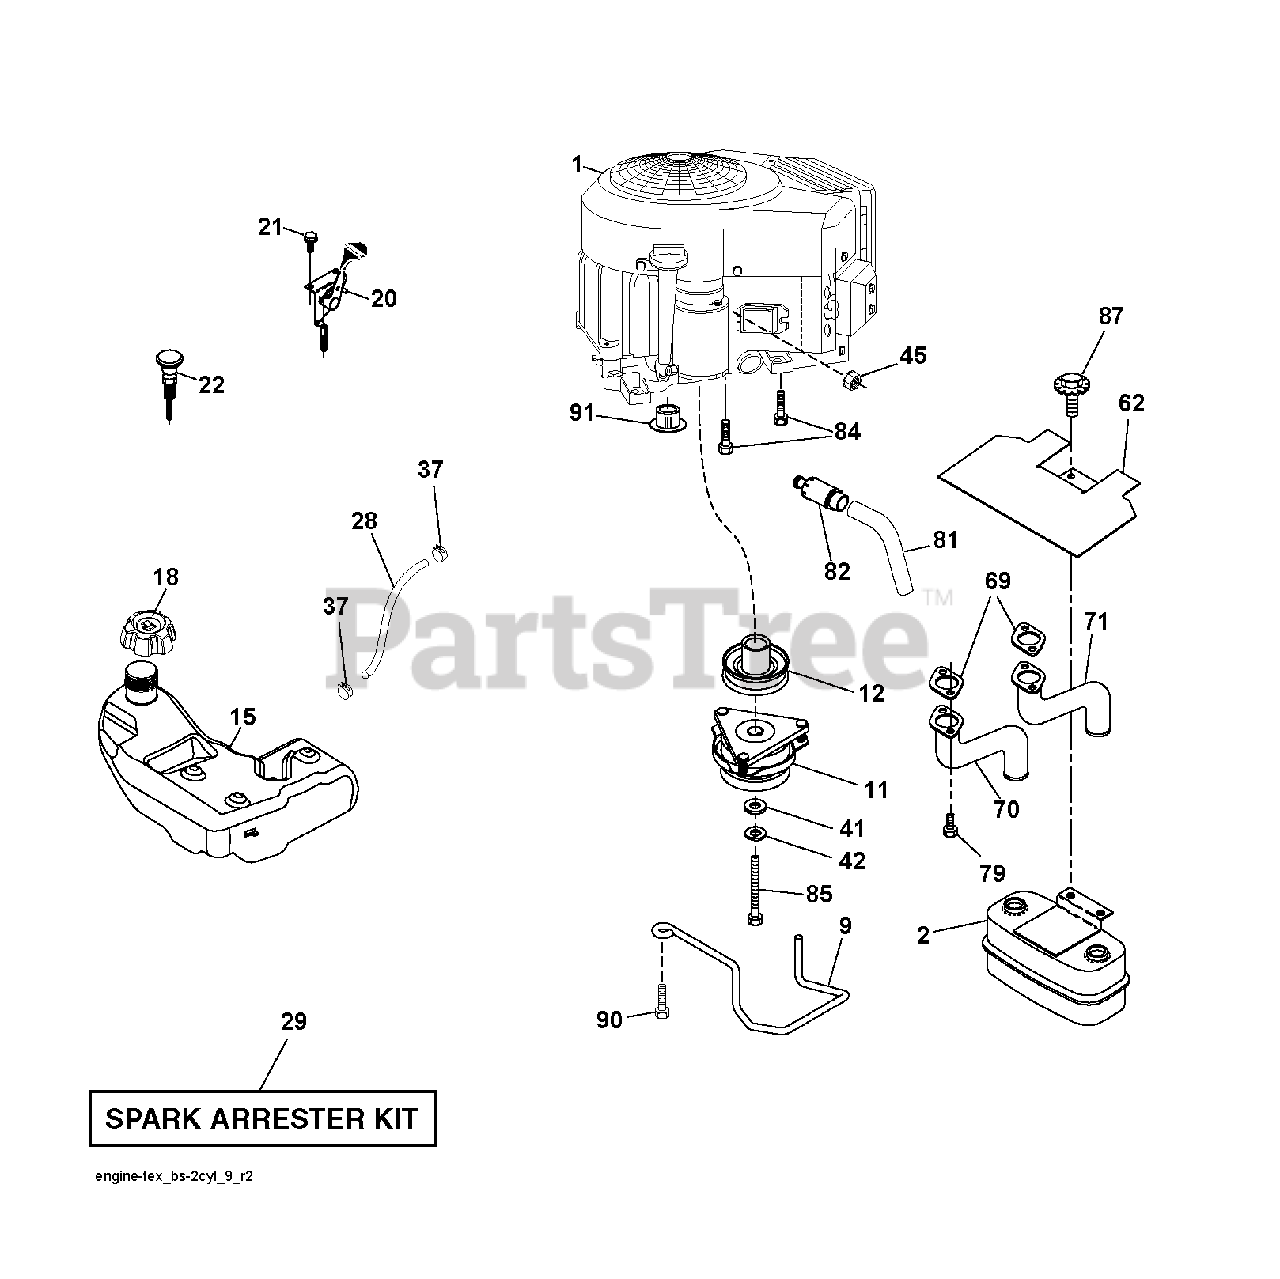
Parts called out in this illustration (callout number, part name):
2	MUFFLER.TWIN.CYL.LOW.TONE
9	KEEPER.BELT.ENGINE.4.2
11	CLUTCH ELECTRIC
12	PULLEY ENGINE
15	TANK.FUEL.4GAL
18	CAP.ASM.FUEL.TANK.3"BL
20	THROTTLE CABLE
21	SCREW.#10 X 0.750.BOS THREAD
22	CONTROL CHOKE
28	LINE.FUEL.20
29	ARRESTER SPARK (OPTIONAL)
37	HOSE CLAMP
42	LOCKWASHER
45	NUT
62	RP SHIELD HEAT MUFFLER
69	GASKET.MUFFLER
70	TUBE MANIFOLD LH
71	EXHAUST TUBE RH
79	SCREW.SOCKET.HEAD.5/16-18
81	TUBE, DRAIN OIL ASM.
82	PLUG DRAIN OIL EASY
84	SCREW.3/8-16
85	BOLT HEX 7/16-20 X 3.75 GR. 5
87	BOLT, 5/16-18 X 1 3/4
90	SCREW 3/8-16X1
91	BUSHING.1.375OD
